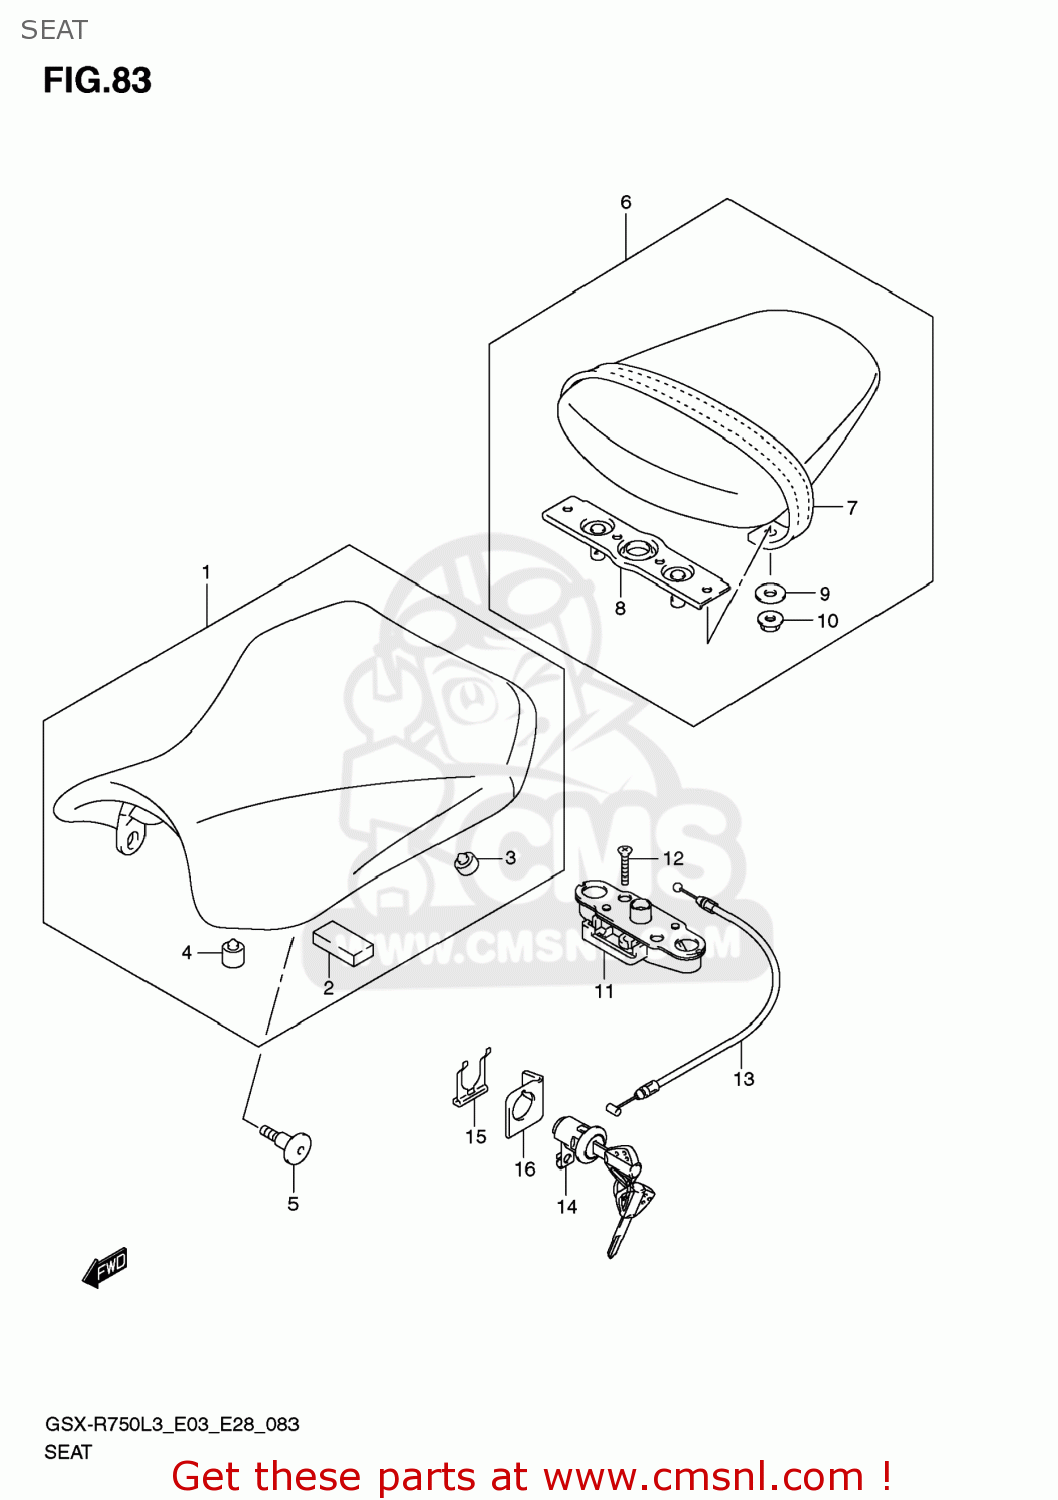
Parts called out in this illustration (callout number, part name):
1	SEAT ASSY
2	CUSHION
3	CUSHION
4	CUSHION
5	SCREW(6X20)
6	SEAT ASSY,PILLION
7	BAND ASSY,SEAT
8	STRIKER
9	WASHER(6.5X20X1.6)
10	NUT
11	BRACKET,SEAT SUPPORT
12	SCREW
13	CABLE,SEAT LOCK
14	LOCK SET,SEAT
15	PLATE,SEAT LOCK ASSY
16	GUIDE,SEAT LOCK CABLE
